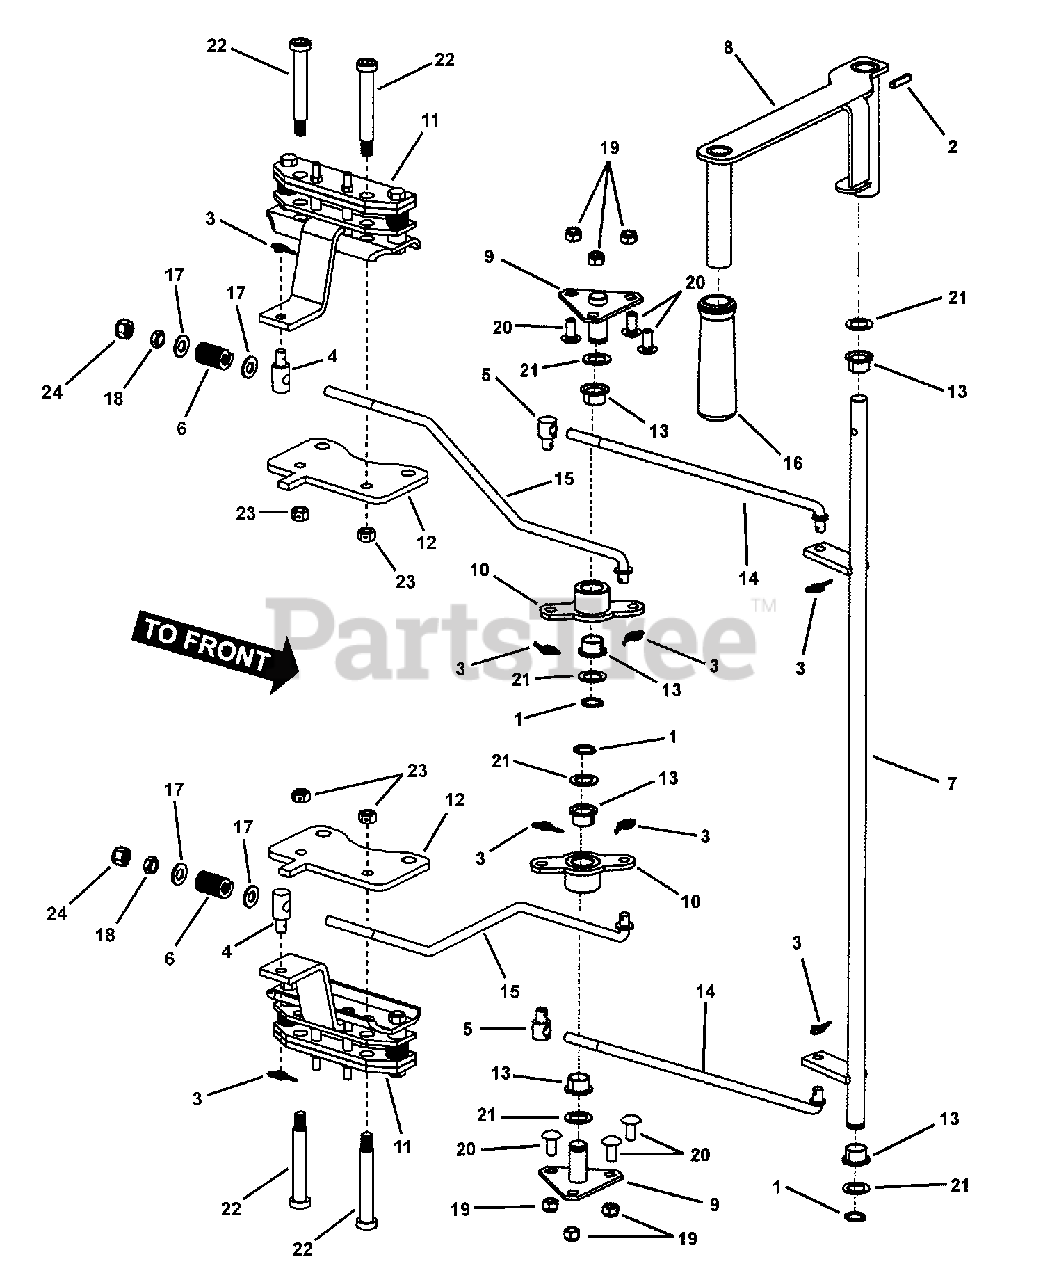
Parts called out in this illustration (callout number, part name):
1	RING, 5/8" External Retaining
2	GROOVE PIN, 1/4 x 1-1/4" long
3	PIN, 3/8" Self Locking Cotter
4	SWIVEL, 3/8" Thru Hole, Special
5	SWIVEL, 3/8-24 Adjustment
6	SPRING, Rectangular Wire Die, Blue
7	WELDMENT, Brake Rod
8	WELDMENT, Park Brake Handle
9	WELDMENT, Park Brake Pivot Bracket
10	WELDMENT, Brake Linkage Bellcrank
11	ASSEMBLY, Brake
12	PLATE, Brake Mounting
13	BUSHING, Teflon Impregnated
14	FRONT LINKAGE, Park Brake (3/8-24 thread)
15	ROD, Brake Rear (3/8-16 thread)
16	GRIP, Parking Brake
17	WASHER, 3/8" SAE Flat
18	NUT, 3/8-24, Hex Jam, GR 5 or B
19	NUT, 5/16-18 HEX NYLON LOCK
20	BOLT, 5/16-18 x 3/4" Short Neck Carriage, GR 5
21	WASHER, .64 I.D. x .99 O.D. x .05 Flat
22	SHOULDER BOLT, 3/8-16 Hex Socket Head
23	NUT, 3/8-16 Hex Center Lock
24	NUT, 3/8-24 Hex Nyloc
